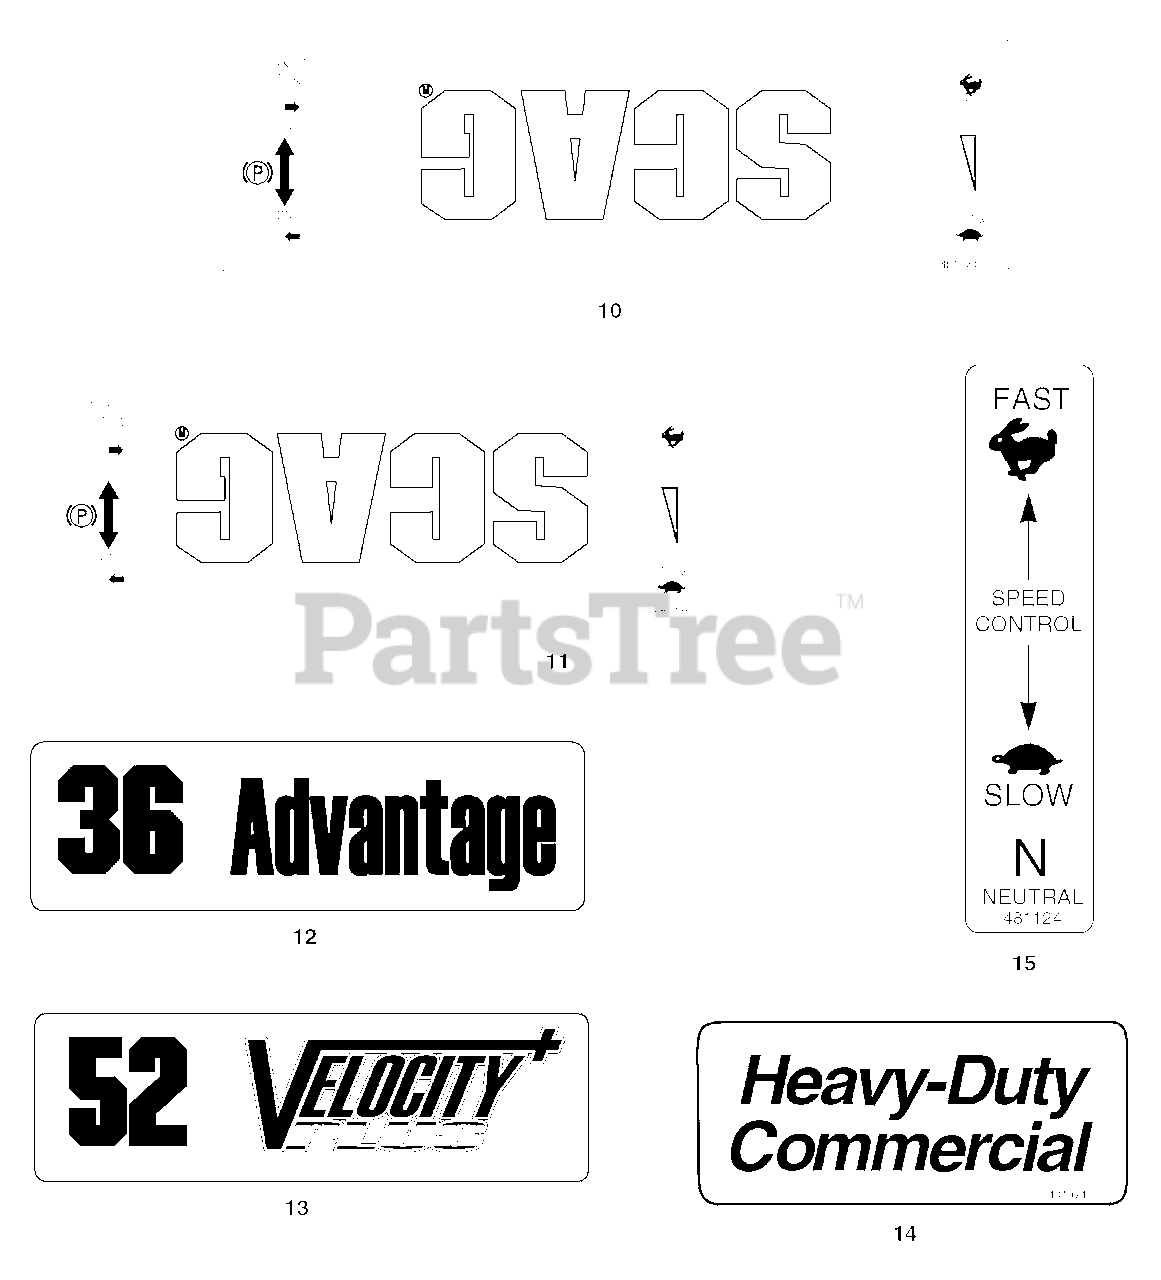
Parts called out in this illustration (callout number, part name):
10	Decal, Instrument Panel - Front
11	Decal, Instrument Panel - Front
12	Decal, 36 Advantage
13	Decal, 48 Velocity Plus
13	Decal, 52 Velocity Plus
13	Decal, 61 Velocity Plis
14	Decal, Heavy Duty Commercial
15	Decal, Speed Control
